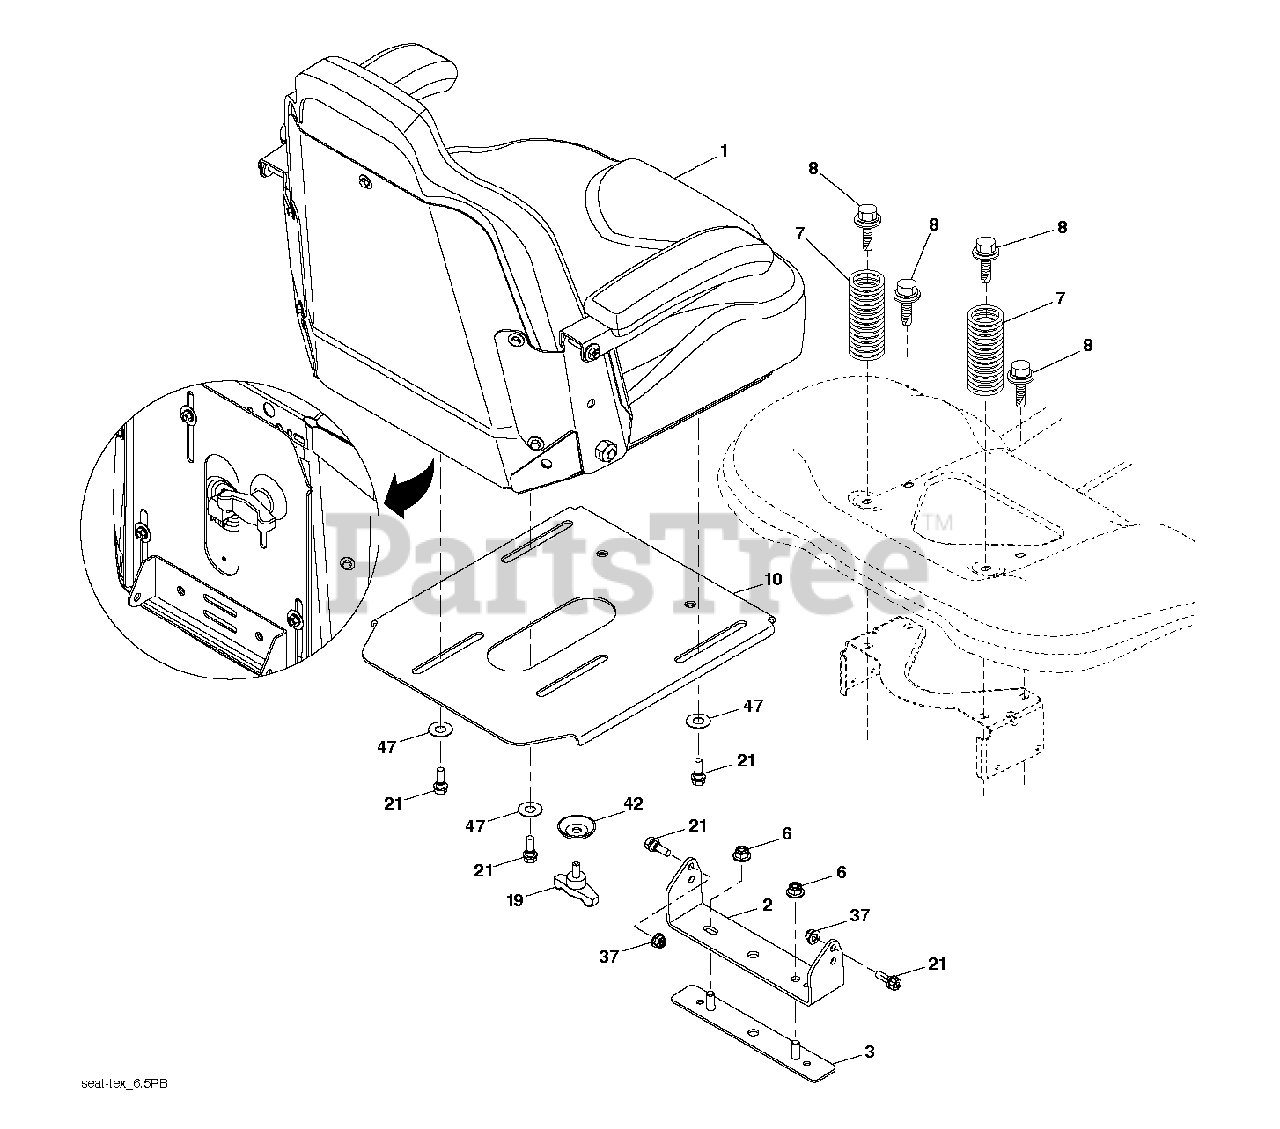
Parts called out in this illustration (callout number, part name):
1	SEAT TRACTOR MZ
2	BRACKET PIVOT FENDER SEAT TRAC
3	BRACKET ASSEMBLY REINFORCEMENT
6	NUT 3/8-16 HEX FLG NYLOC ZD
7	SPRING COMPRESSION SEAT 300 SE
8	BOLT, 5/16-18 X 1 3/4
10	Bracket Assembly Plate
19	KNOB SEAT 5/16-18X3/4
21	BOLT SHOULDER 5/16-18 UNC
37	5/16-18 NYLOC FLANGE NUT
42	WASHER.CUP.SEAT.
47	WASHER NYLON .50 X 1.00 X .045
